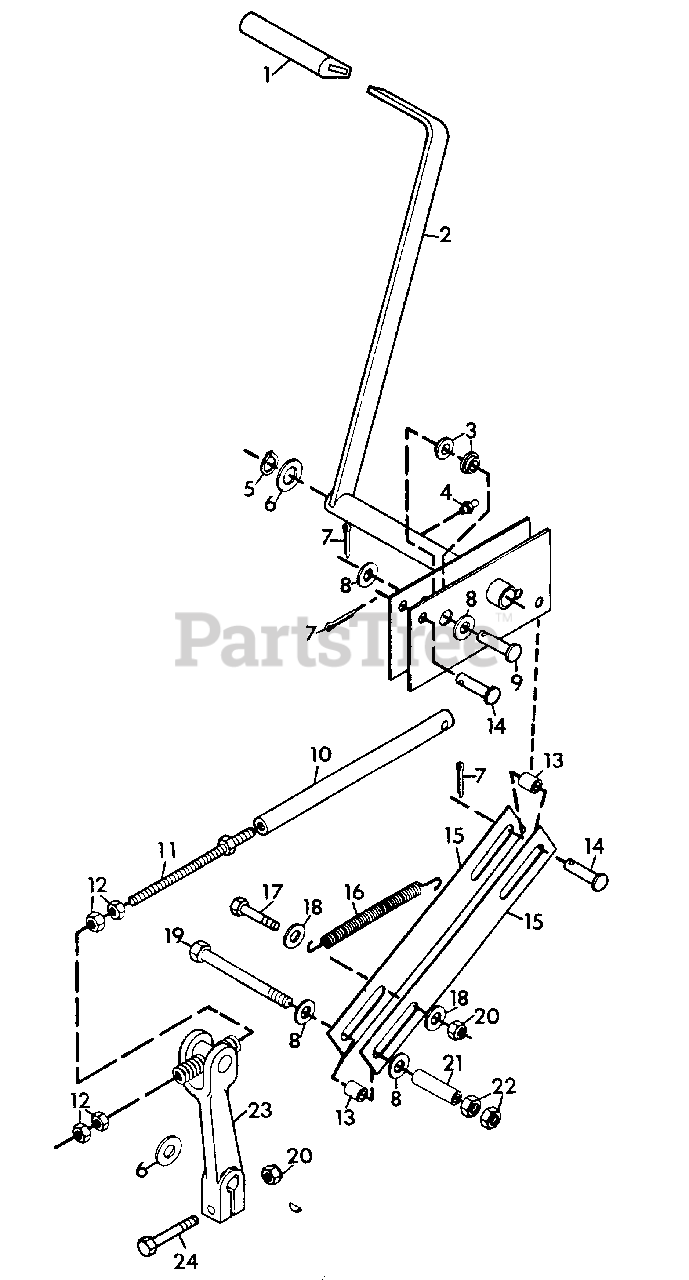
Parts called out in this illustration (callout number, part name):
1	GRIP, HANDLE
2	LEVER, FWD-REV
3	BUSHING, NYLON
4	FITTING, LUBE 1/4-28
5	RING, RETAINING .750 SHAFT
6	WASHER, FLAT .812X1.496X.134
7	PIN, COTTER .125X.750
8	WASHER, FLAT .406X.812X.065
9	PIN, CLEVIS .375X1.250
10	ROD, CONTROL FWD-REV
11	ROD, CONTROL EXTENSION
12	NUT, JAM 3/8-16
13	SPACER
14	PIN, CLEVIS .375X1.31
15	STRAP, NEUTRAL DETENT
16	SPRING, EXT. 5.5X.5X20 RATE
17	BOLT, HEX 5/16-18X1.25
18	WASHER, FLAT .344X.688X.065
19	BOLT, HEX 3/8-16X3.25
20	NUT, LOCK 5/16-18
21	SPACER
22	NUT, LOCK 3/8-16
23	LEVER, CONTROL
24	BOLT, HEX 5/16-18X2.00
